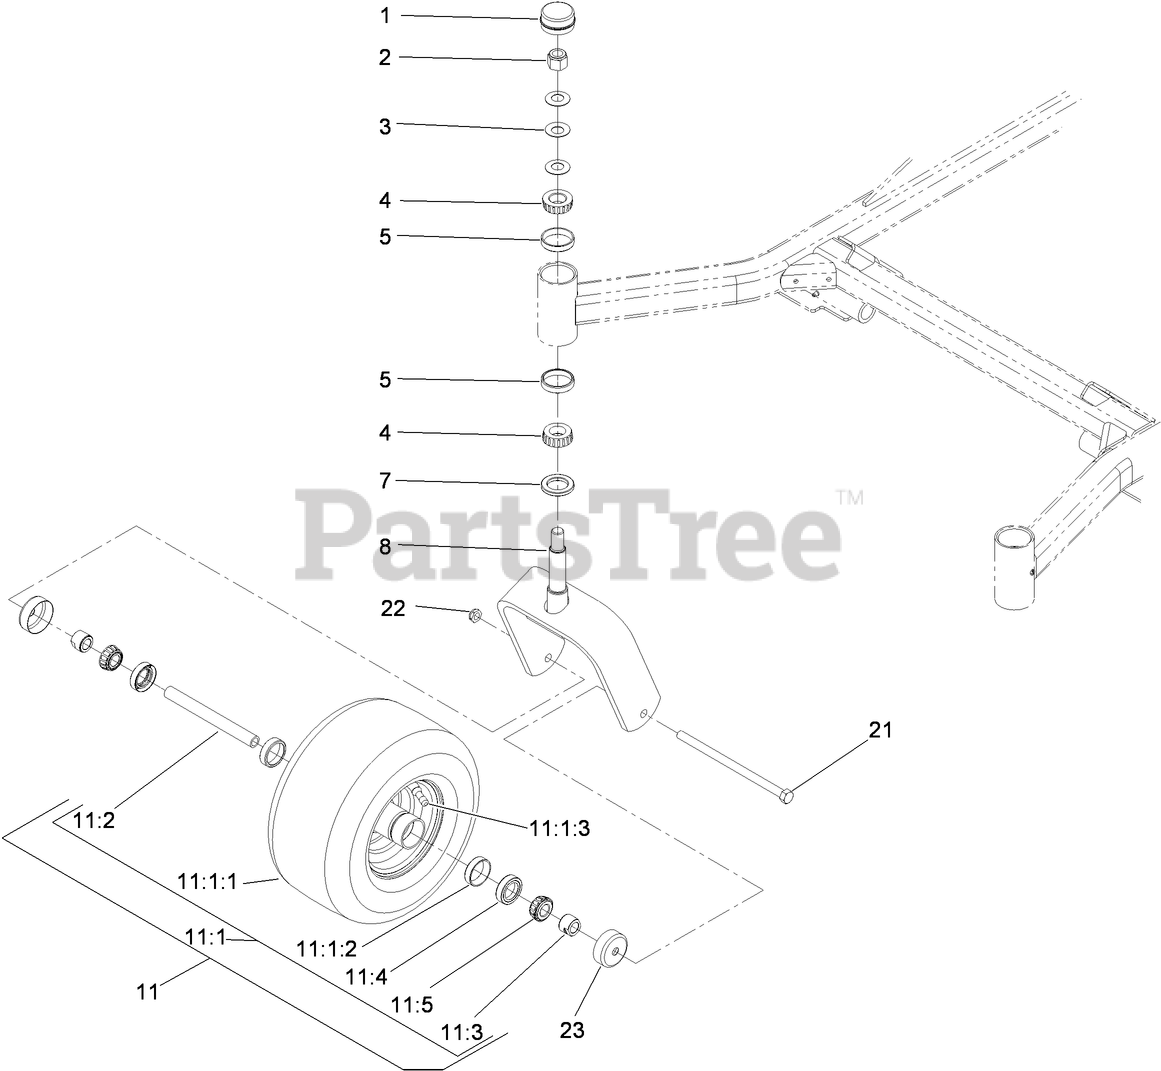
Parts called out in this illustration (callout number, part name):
1	CAP-GREASE
2	NUT-LOCK, NI
3	WASHER-BELLVILLE
4	BEARING-CONE, TAPERED
5	BEARING-CUP, TAPERED
7	SEAL-GREASE
8	CASTER-FORK
11	WHEEL ASM
11:1	WHEEL AND TIRE ASM
11:1:2	BEARING-CUP
11:1:3	VALVE
11:2	AXLE-CASTER
11:3	SPACER-NUT
11:4	SEAL-CASTER
11:5	BEARING-CONE, TAPER
21	Screw-HH
22	NUT-LOCK, NI
23	GUARD-SEAL
